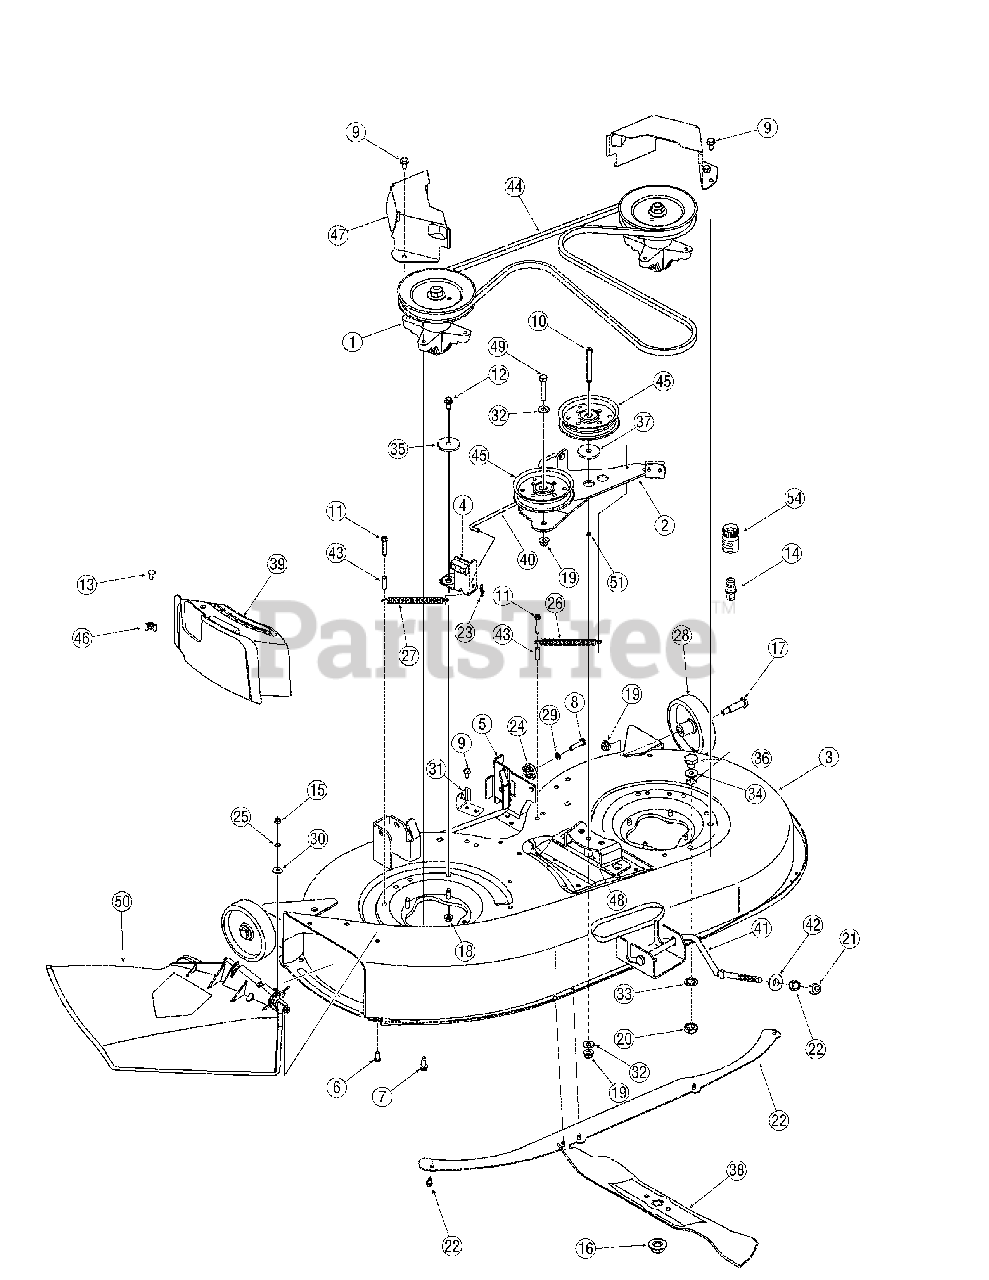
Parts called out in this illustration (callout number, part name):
1	Spindle Assembly, Pul, 6.3" Dia
3	Deck Shell, 42" (w/o Wheel Brkt)
6	Screw, 1/4-20, .75, Gr5
7	Screw, 5/16-18, 0.750
8	Screw, 5/16-18, 1.250
9	Screw, 5/16-18, 0.625
10	Screw, 3/8-16, 3.50, Gr5
11	Screw, 1/4-20, 1.500
12	Screw, 5/16-18, .75, Gr5
13	Carriage Screw, , 1/4-20 x .62
14	Deck Water Nozzle
15	Nut, Hex, 1/4-20, Gr5
16	Nut, Flange, 5/8-18
17	Screw, Shldr, .498 x 1.53, 3/8-16
18	Nut, Flange Lock, 5/16-18, GrF
19	Nut, Flange Lock, 3/8-16, GrF
20	Nut, Hex, M16-1.5
21	Nut, Hex Lock, 1/2-13, Gr8
22	Nut, Hex, 1/2-13, Gr5
23	Pin, Cot, .072 Dia. x 1.13 Lg
24	Gear, Deck Adjustment
25	Nut, Push, .25 ID x .50 OD
26	Spring, Exten. , .75 Dia. x 6.375
27	Spring, Exten. , .50 Dia. x 6.375
28	Wheel, Deck 5.0 x 1.38
29	Washer, Lock, 5/16
30	Washer, Bell, .265 x.75 x .062
32	Washer, Flat, .385 x .87 x .06
33	Washer, Lock, 5/8, Internal Tooth
34	Washer, Flat, .64 x 1.24 x .06
35	Spacer, Shoulder, .5000 x .1475
36	Plug, Screw, M16 x 1.5
37	Spacer, Shoulder, .8840 x .190
38	Blade, 21.23", Star 3-in-1
39	Mulch Plug
40	Control Rod, Brake
41	Deck Rod, Front Adjustable
42	Pivot Cup, Deck Lift
43	Spacer, .260 x .372 x 1.030
44	Belt, V-Type
45	Idler Pulley, 4.25" Dia.
46	Wing Nut, 1/4-20
48	Spacr, 3/8 ID x .68 OD x 1.46 Lg.
49	Screw, 3/8-16 x 1.75
50	Chute Assembly, Discharge
51	Nut, Push, 3/8
52	Screw, 1/4-20, 0.500
54	Water Nozzle Adapt
